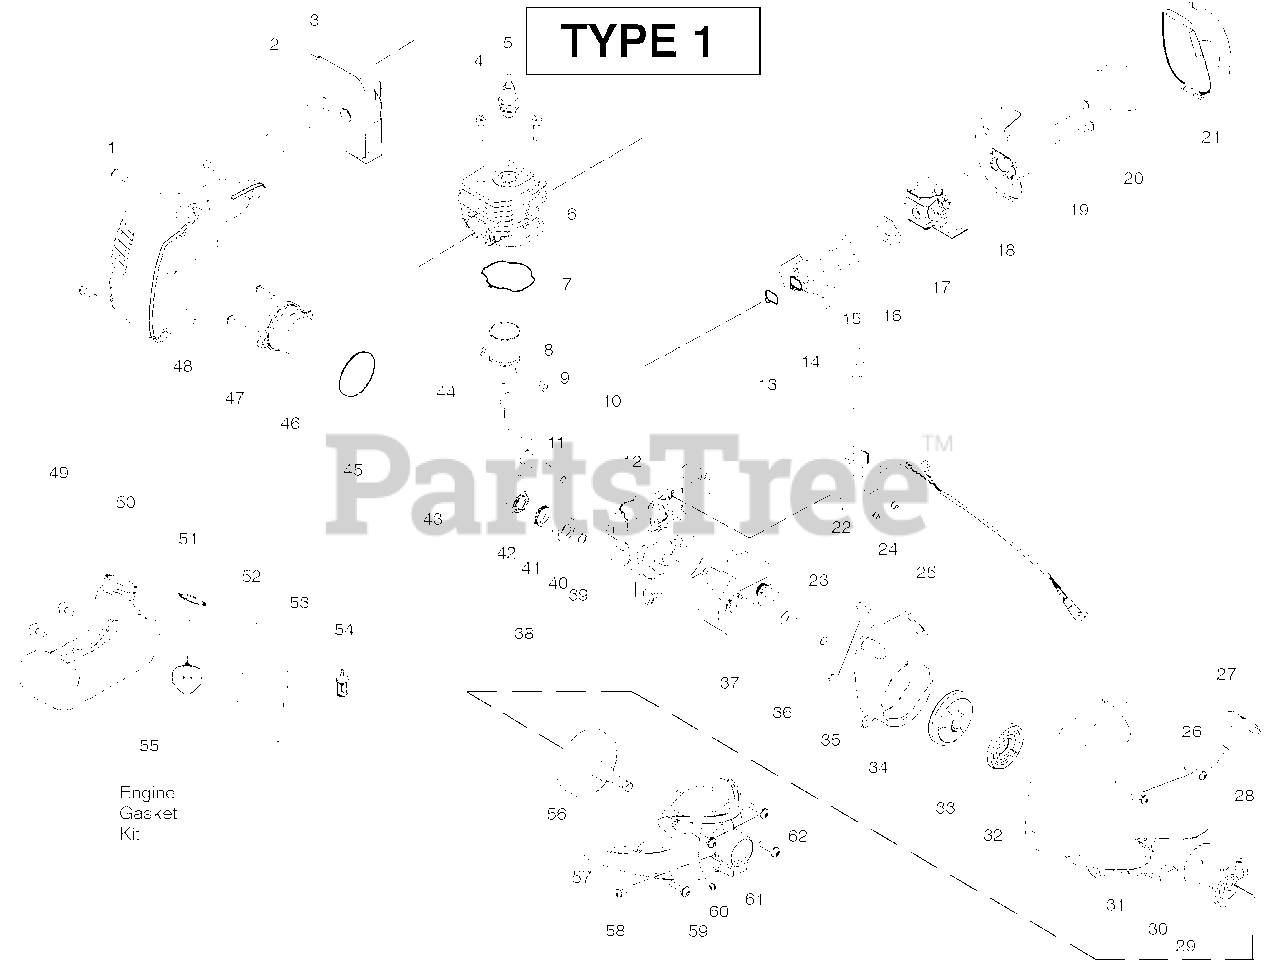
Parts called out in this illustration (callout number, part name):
2	Bolt-Muffler
3	Assy-Muffler/Shield
4	Screw-Cylinder
5	Spark Plug (RCJ 6Y)
6	Cylinder
7	Seal-Cylinder (kit)
8	Piston Ring
9	Retainer-Piston Pin
10	Kit - Piston
11	Assy-Crankshaft
12	Assy-Crankcase
13	Seal-Cyl/Carb.(kit)
14	Adapter-Carb.
16	Gasket-Carb. (kit)
17	Kit-Carb.(C1U-W19)
20	Foam-Air Filter
21	Cover-Air Box
22	Ignition Module
23	Spacer-Flywheel
25	Assy-Switch wire
27	Handle-Starter
28	Kit - Rope
29	Assy-Clutch
30	Washer-Clutch
31	Assy.-Fan Hsg
32	Spring-Starter
33	Kit-Starter Pulley
36	Washer-Clutch Flat
37	Assy-Flywheel
38	Assy-C'case & C'shaft
39	Retain. Ring-C'shaft
40	Outer Bearing
41	Seal-C'shaft
42	Inner Bearing
43	Kit-piston/rod
44	Kit-Conn. Rod
45	O-Ring-C'case (kit)
46	Assy-Plug (incl.45)
48	Shroud-Rear
49	Retainer-Tank
50	Assy-Fuel Tank
51	Assy-Fuel Cap
52	Kit-Fuel Line (Small)
53	Kit-Fuel Line (Large)
54	Assy-Fuel Pickup
55	Kit-Engine Gasket
56	Assy-Clutch Drum
57	Assy-Clutch Cover
58	Screw-Align
60	Screw 12-24
61	Nut 12-24
